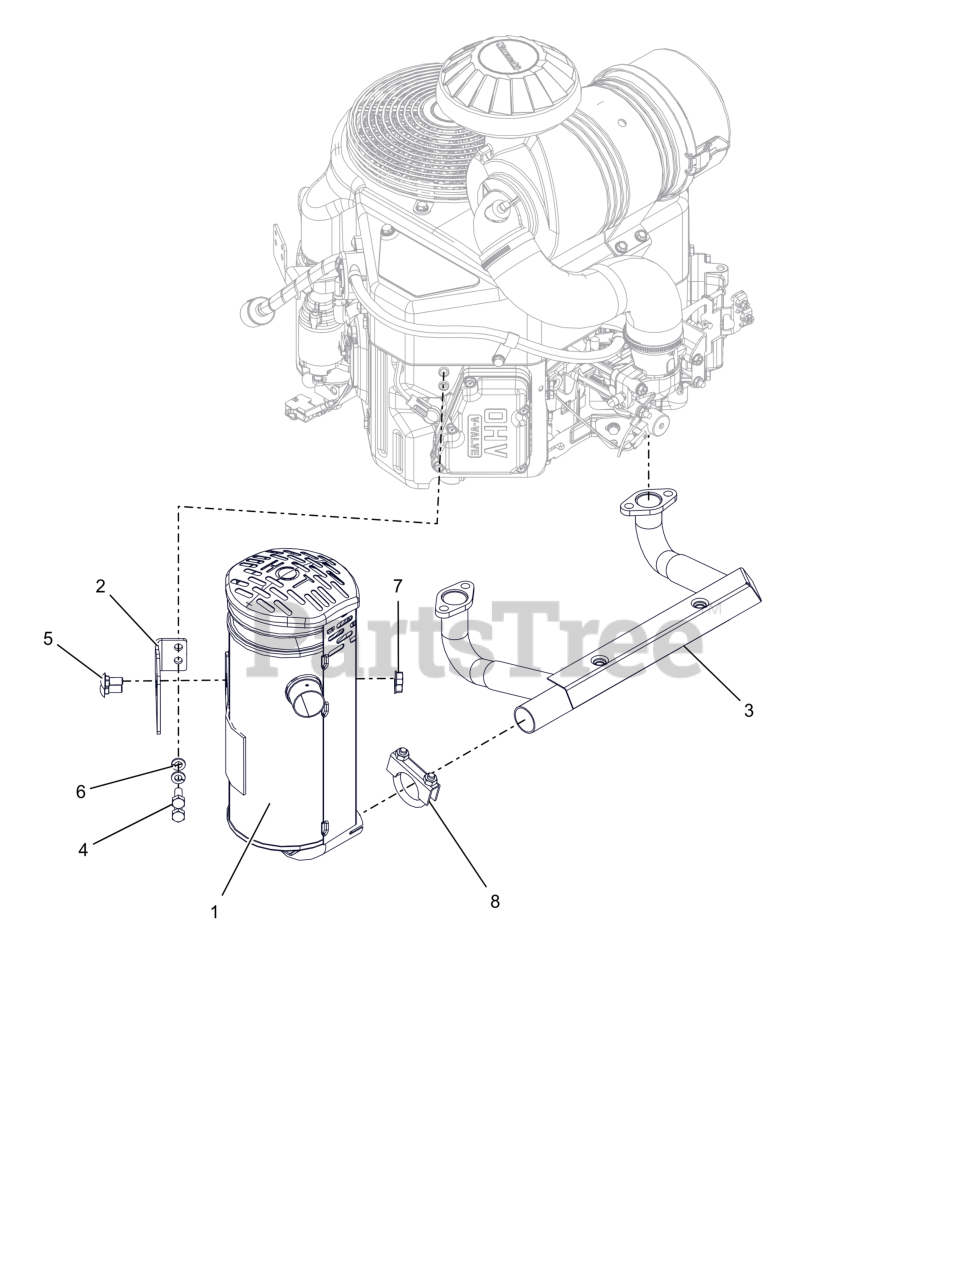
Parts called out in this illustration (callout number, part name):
1	MUFFLER, PROSTANCE
2	BRKT, MUFFLER MOUNT - FT730
3	MANIFOLD, PROSTANCE EXHAUST
4	BLT, HEX M8-1.25X20 G8.8 ZCC
5	BLT,RHSN .31-18X.75 G5 ZCC
6	WSHR,LK-REG .312X.078 ZCC
7	NUT,LK-CTR-FLG .31-18 GF ZCC
8	CLAMP, MUFFLER - 1.438
